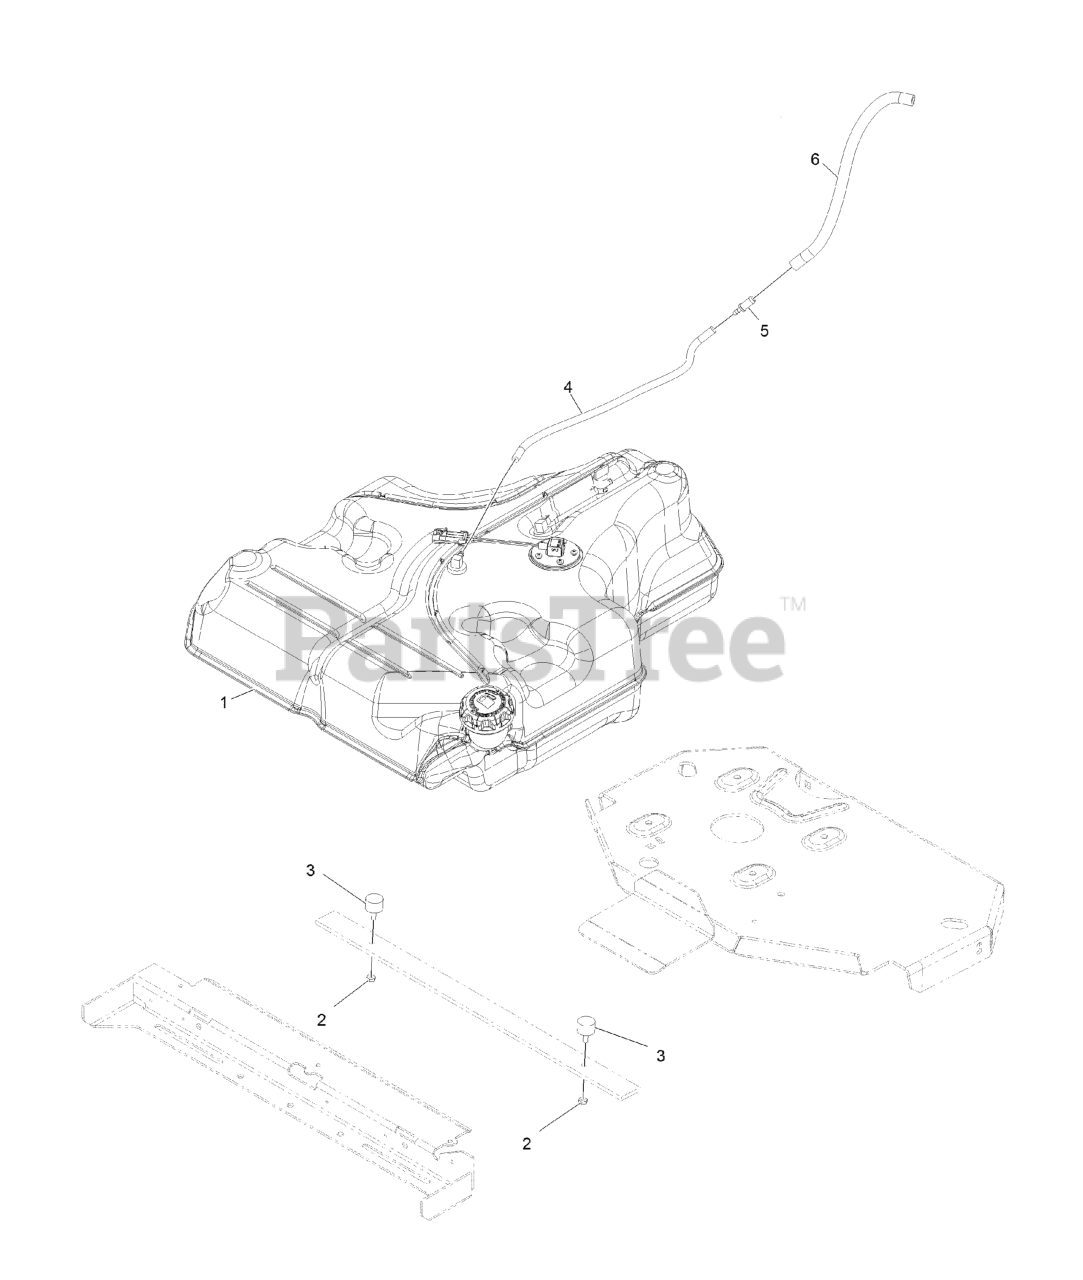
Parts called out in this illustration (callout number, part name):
1	FUEL TANK ASM
2	NUT-JAM
4	HOSE-FUEL
5	FITTING-STRAIGHT
6	HOSE-FUEL
